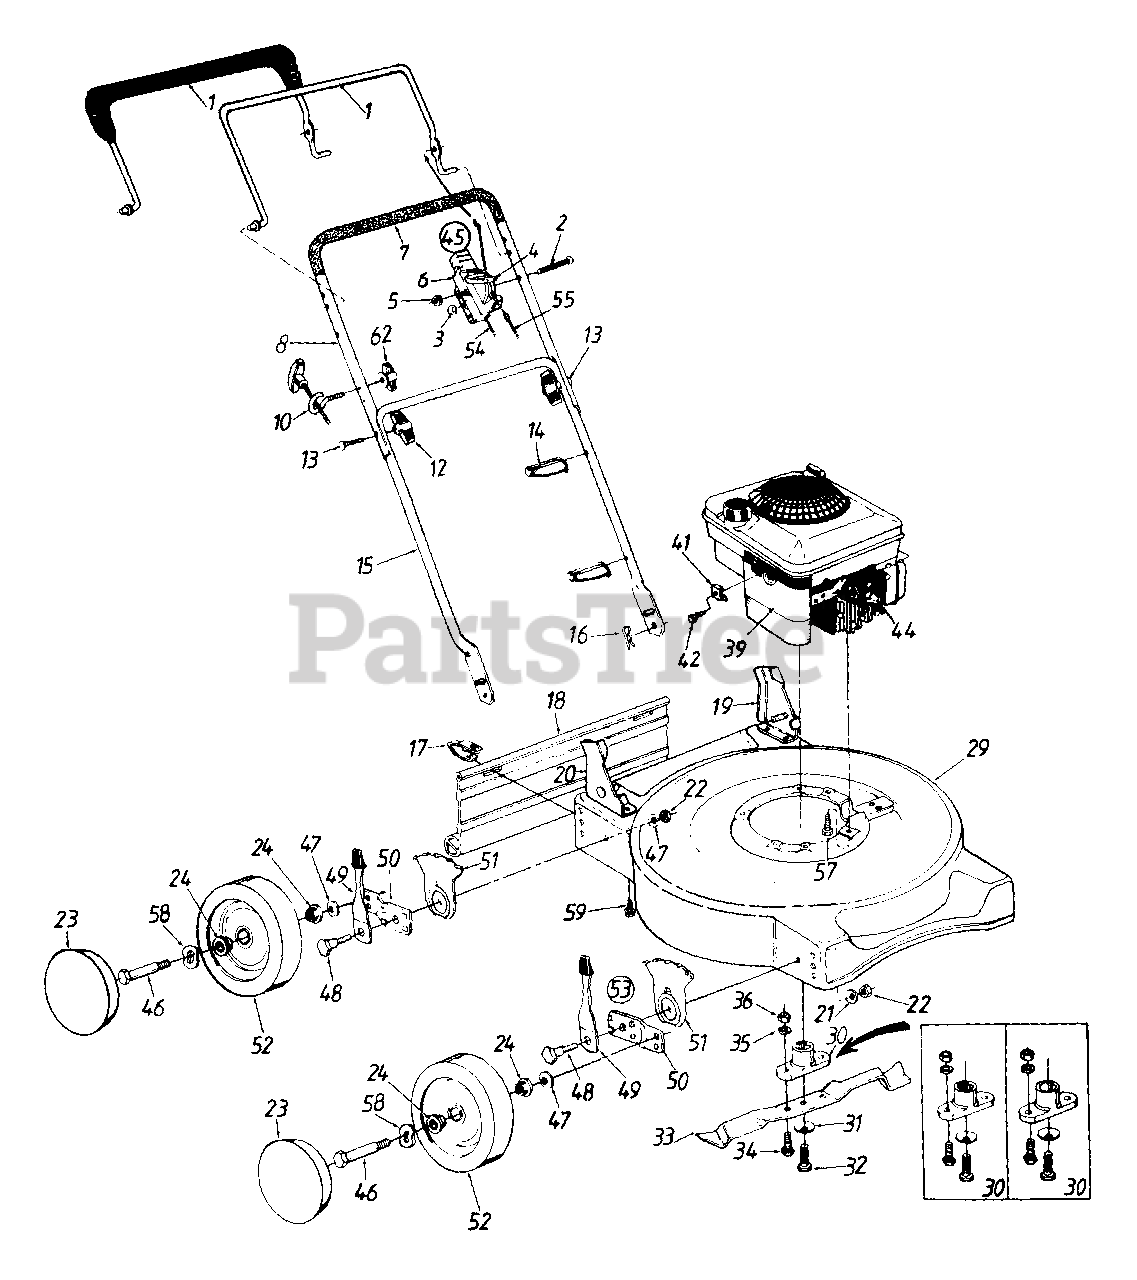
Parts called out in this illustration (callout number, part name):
1	Control Handle Ass'y.
2	Oval C-Sunk Scr.
3	Spr. Wash..66" I.D.
4	Throttle Lever
5	Hex L-Nut 1/4-20 Thd.
6	Throttle Body
7	Grip
12	Hand Knob
13	Curved Hd. Bolt 5/16-18 x 2" Lg.
14	Cable Tie
16	Hairpin Cotter
17	Hinge Clip
18	Rear Flap
22	Hex Nut 3/8-16 Thd.
23	Hub Cap
24	Bearing
29	20" Deck Ass'y.
30	Blade Adapter Kit
31	Bell-Wash..39" I.D.
32	Hex Bolt 3/8-24 x 1.5" Lg.
33	20" Mulching Blade
34	Hex Bolt 3/8-24 x 1" Lg.
35	L-Wash. 3/8" I.D.
36	Hex Nut 3/8-24 Thd.
39	Engine
41	Cable Clamp
42	Hex Self-Tap Scr #10-32 x 62"
44	Spark Plug Boot
45	Throttle Box Comp
46	Axle Bolt
47	Bell-Wash..400" I D. x 88"
48	Shld. Bolt 50" Dia. x 357"
49	Spring Lever Ass'y w/Knob
51	Height Adj. Plate
52	Wheel Ass'y Comp
53	Height Adj. Ass'y. Comp - R.F. & L.R.
54	Throttle Cable - 51" (B&S)
55	Control Cable - 39" (B&S)
57	Hex L-Wash. Hd. Scr. 3/8-16 x 10" Lg.
58	Wave Washer 51" I.D.
59	Hex Wash. Hd B-Tap Scr 5/16-18 x .5" Lg.
62	Wing Nut 1/4-20 Thd.
